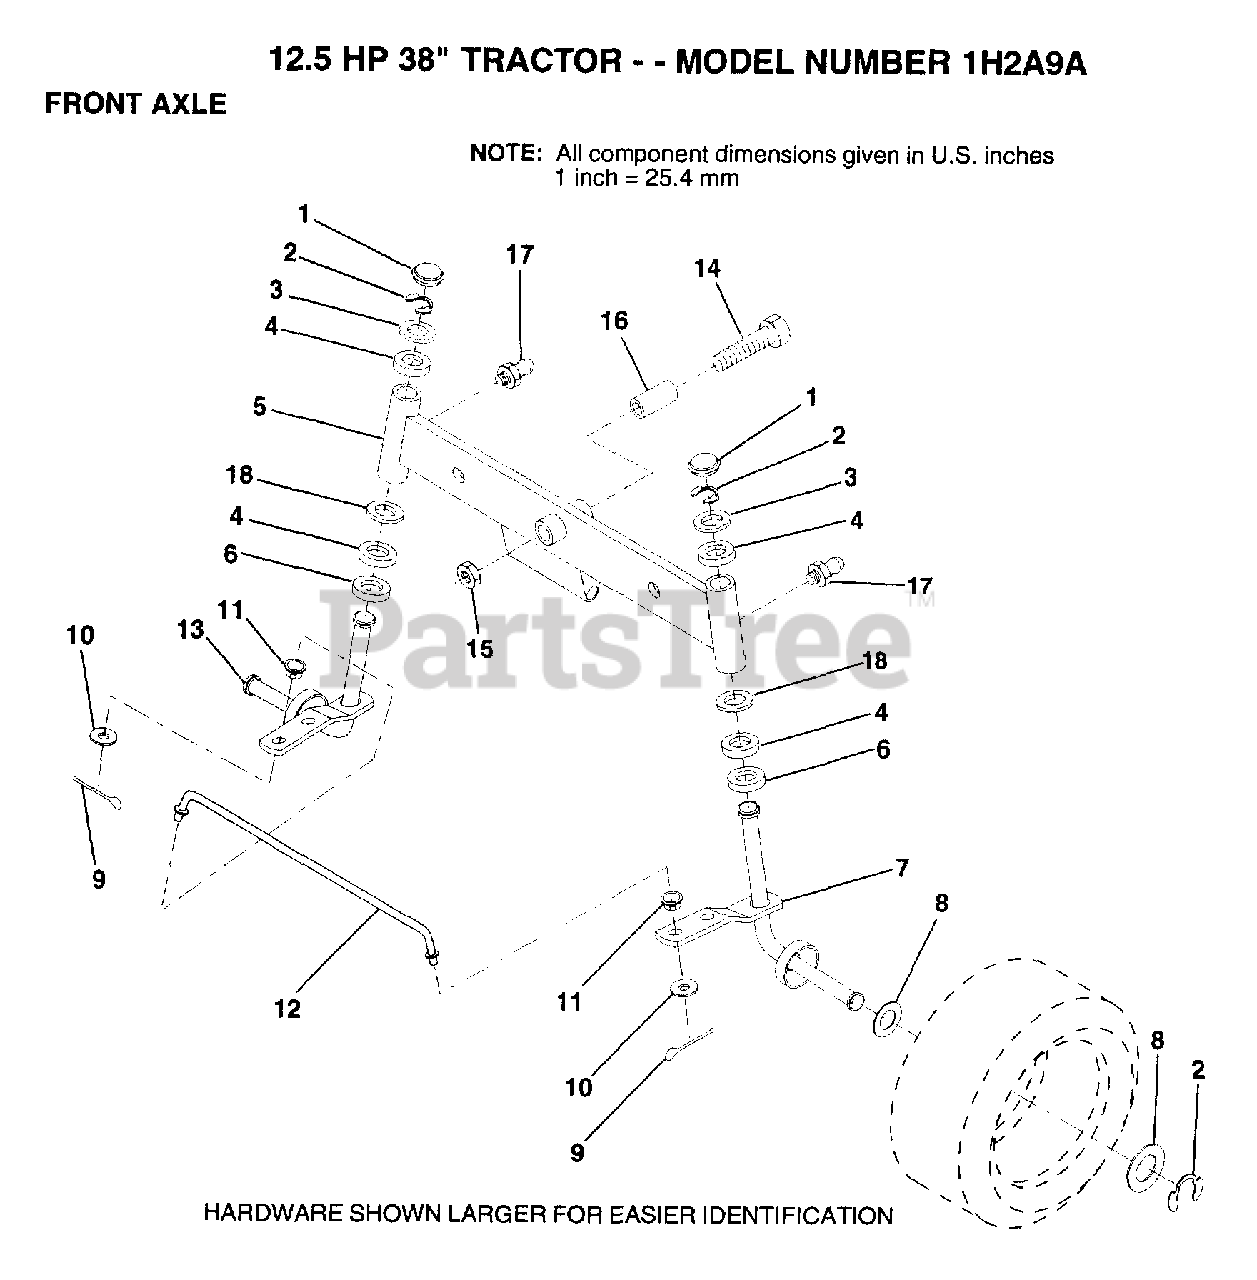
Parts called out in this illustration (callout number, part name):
1	CAP
2	RING
3	WASHER
4	COL. SRTG. BEAR.
6	WASHER .T
7	SPINDLE ASM RH
8	WASHER
9	COTTER PIN
10	WASHER
11	BUSHING.DRAGLINK
12	TIE ROD
13	SPINDLE ASM LH
14	BOLT HEX 5/8-11
15	"NUT-LOC,FLANGE LT"
16	BEARING
17	ZERK M
